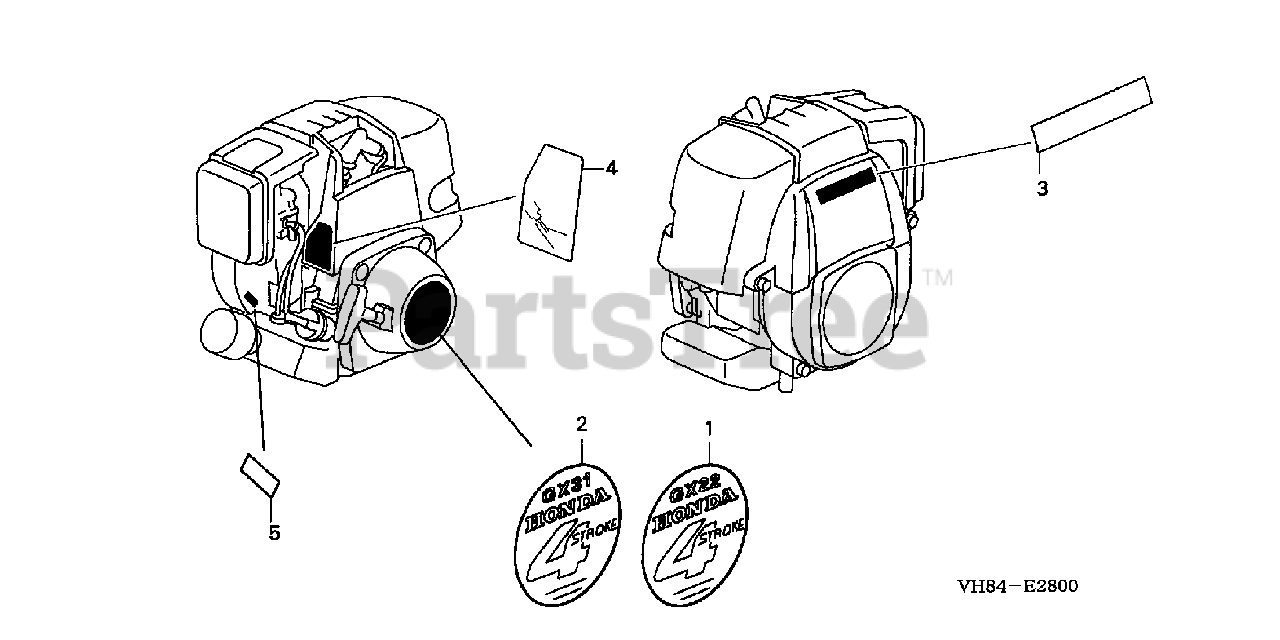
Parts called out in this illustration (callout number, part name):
2	EMBLEM (GX31)
3	MARK, HONDA
4	MARK, OIL CAUTION
4	MARK, OIL CAUTION (ENGLISH)
5	MARK, TYPE (GD4)
